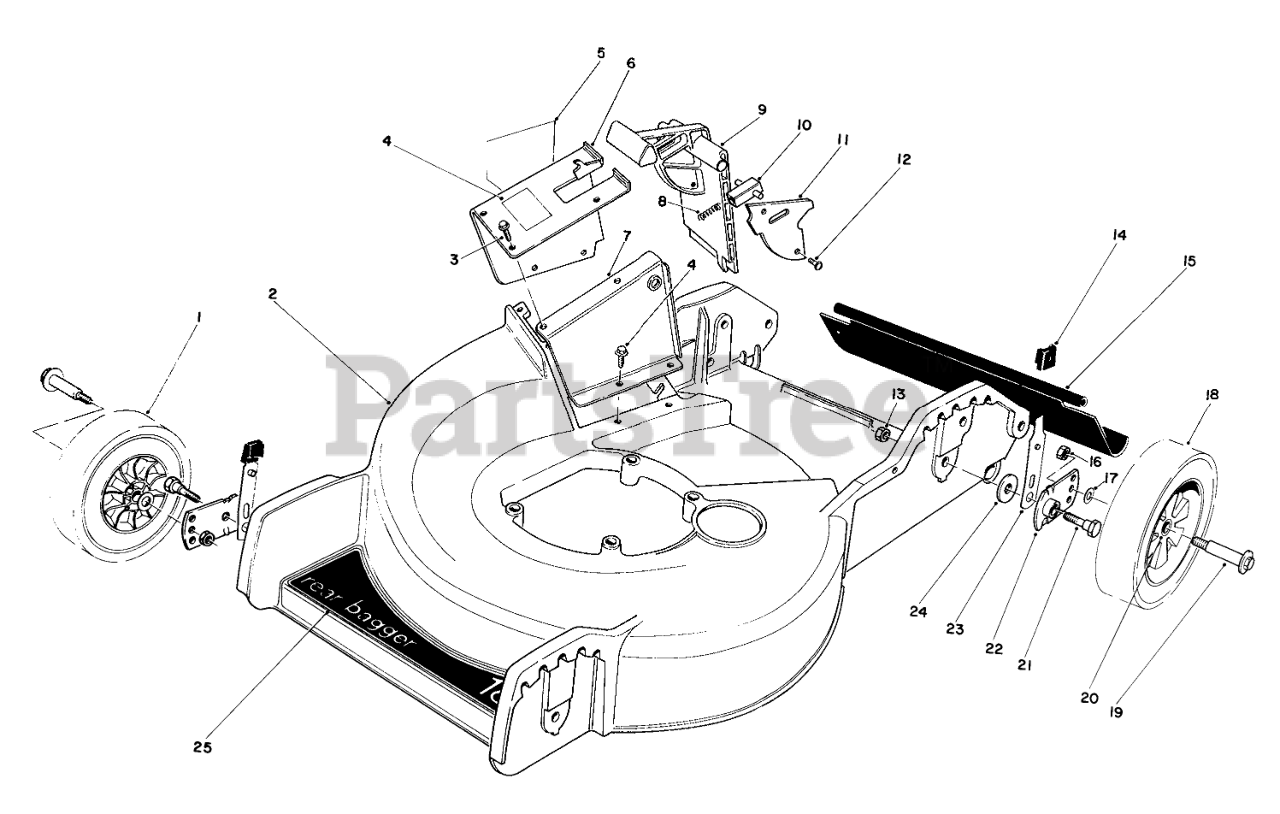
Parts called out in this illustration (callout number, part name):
1	Wheel & Tire Assembly (Incl. Ref. #20)
2	Housing
3	SCREW
4	Decal-Door
5	DECAL-DANGER
6	Tunnel-Outer (Incl. Ref. #4 & 5)
7	Inner Tunnel
8	SPRING-COMPRESSION, LATCH
9	Door Mulching
10	Door Latch
11	Cover Door
13	NUT-LOCK, NI
14	KNOB-ARM
15	SHIELD - TRAILING
16	Nut
17	WASHER
18	Wheel & Tire Assembly (Incl. Ref. #20)
19	BOLT-WHEEL
20	BUSHING
21	PIVOT SCREW
22	PIVOT ARM ASSY
23	SPRING ARM ASM
24	PIVOT WASHER
25	DECAL-DECK
